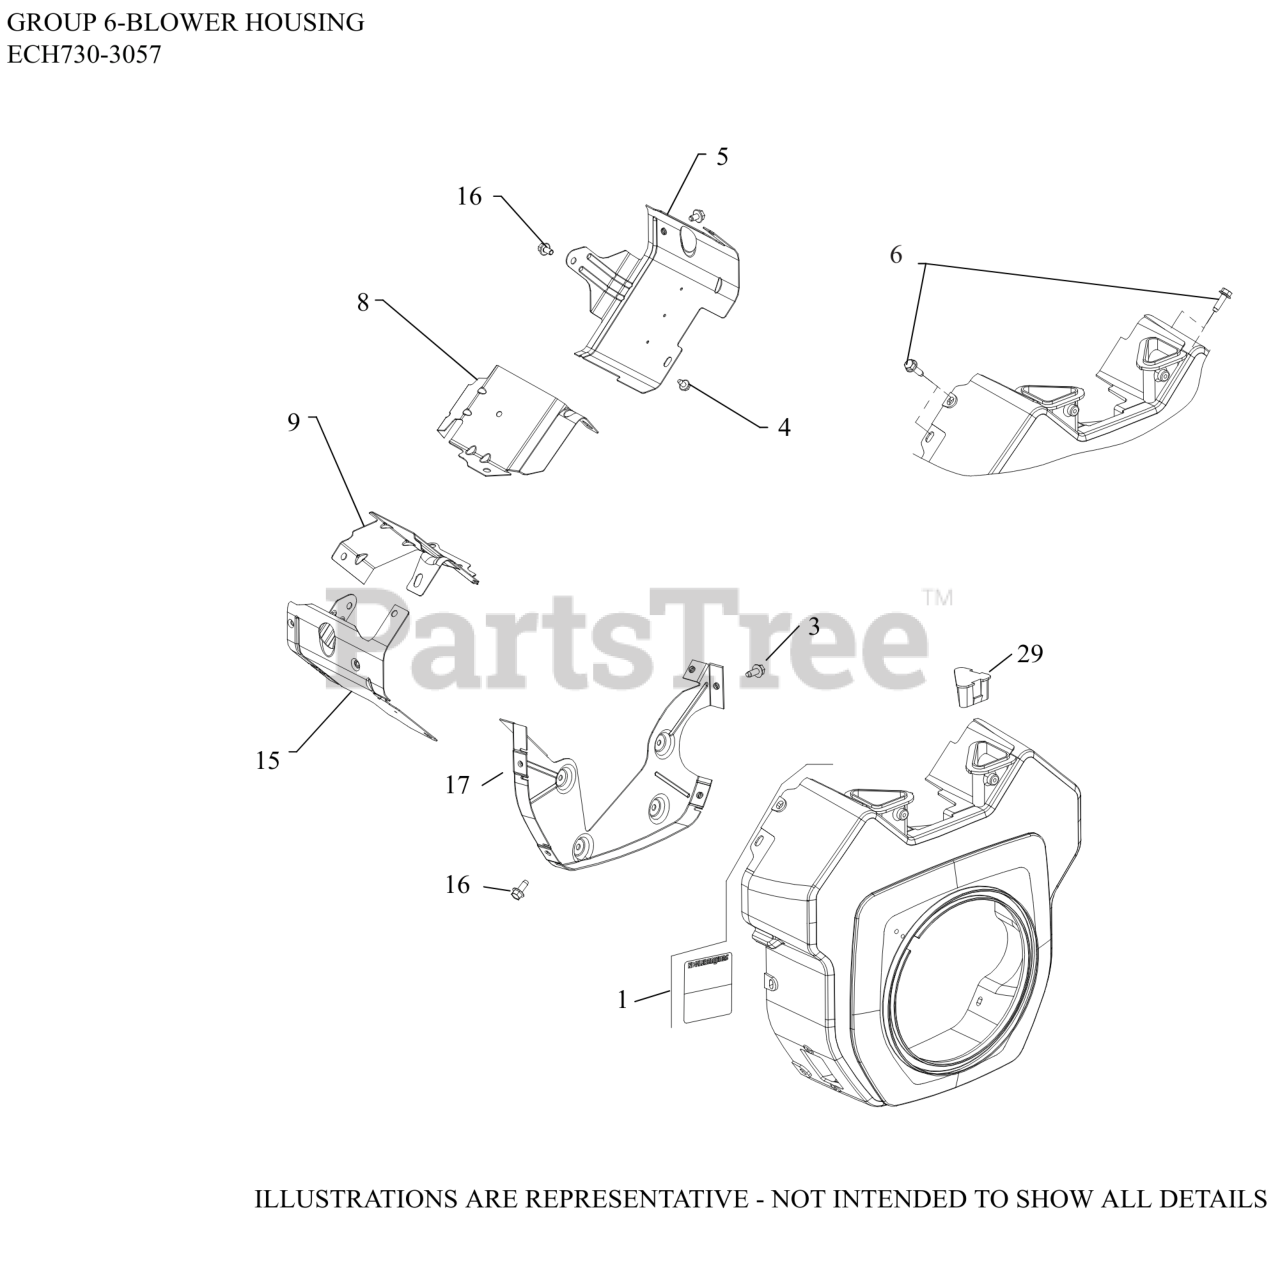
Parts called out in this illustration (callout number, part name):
1	HOUSING, BLOWER
3	SCREW, THREAD FORMING
4	SCREW, THREAD FORMING
5	KIT, RIGHT BARREL
6	SCREW, THREAD FORMING
8	BAFFLE, VALLEY #1 CYLINDER
9	BAFFLE, VALLEY #2 CYLINDER
15	BAFFLE LEFT BARREL
16	SCREW, THREAD FORMING
17	PLATE, BACKING
17	KIT, BACKING PLATE
29	COVER, BLOWER HOUSING
